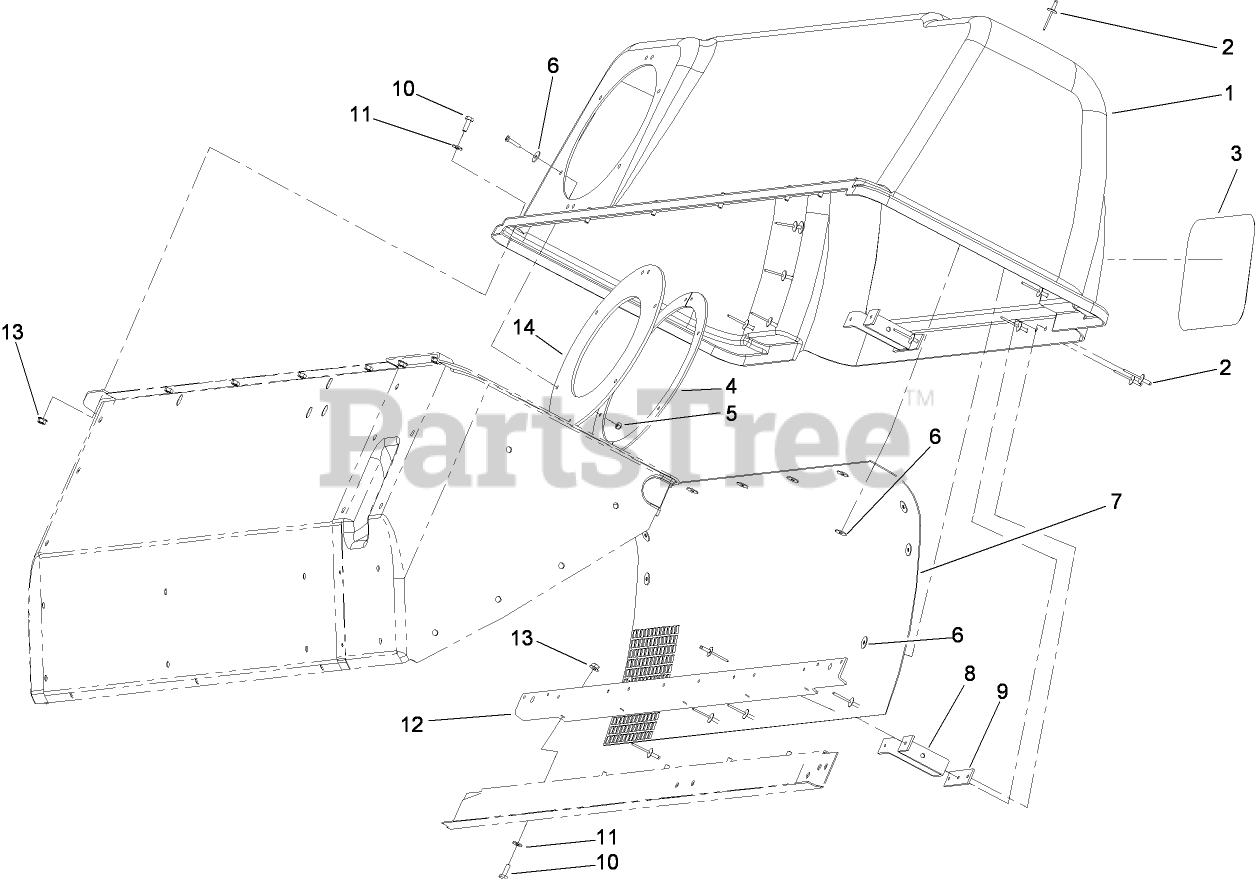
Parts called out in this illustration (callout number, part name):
1	HOOD ASM
2	RIVET-BLIND
3	DECAL
4	CLAMP-SEAL
5	NUT-LOCK, NI
6	WASHER-FLAT
7	Screen-Bagger
8	Bracket-Mount
9	Plate-Latch, Reinforcement
10	SCREW-HH
11	WASHER-FLAT
12	SUPPORT-SCREEN
13	NUT-HF
14	SEAL-TUBE
